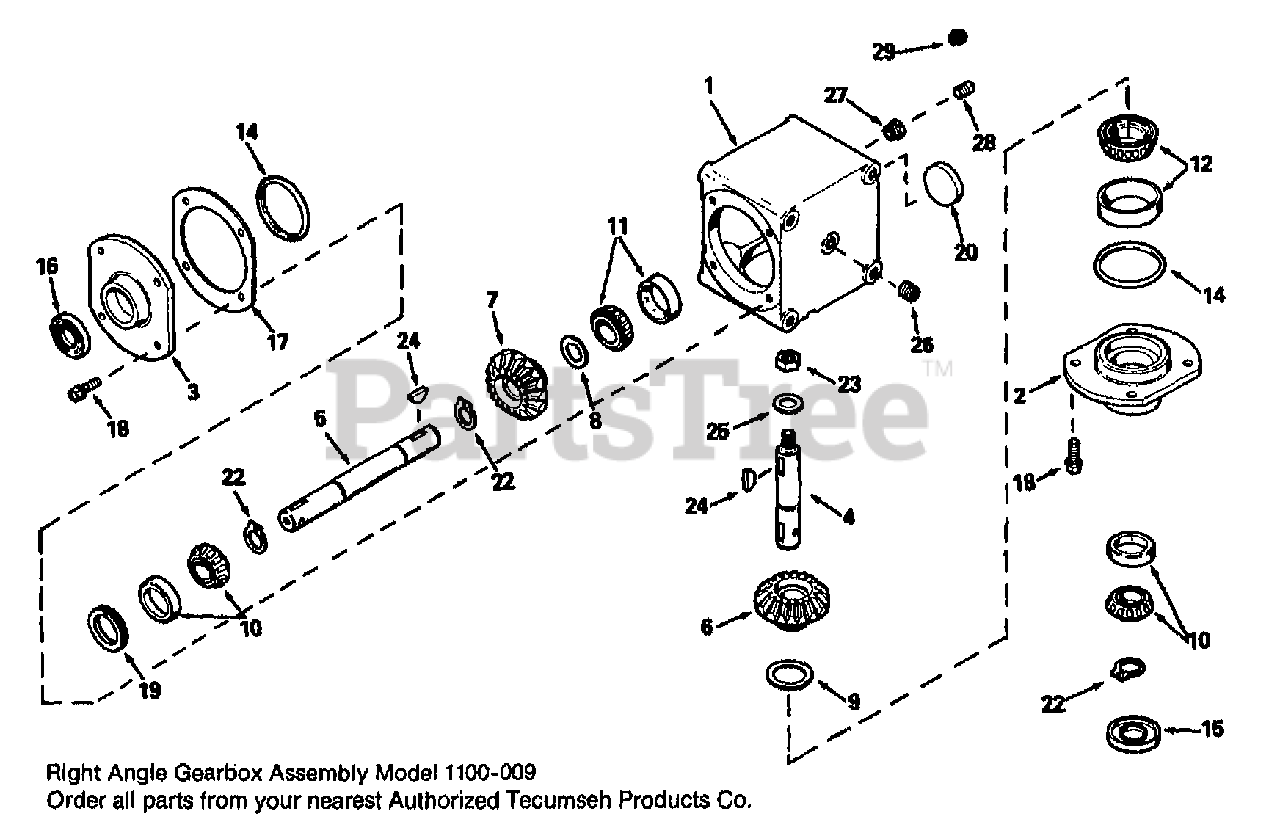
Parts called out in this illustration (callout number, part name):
4	OUTPUT SHAFT
5	INPUT SHAFT
6	BEVEL GEAR
7	BEVEL GEAR
8	SHIM STOCK
9	SHIM STOCK
10	BEARING & CUP
11	BEARING & CUP
12	BEARING & CUP
15	OIL SEAL
16	OIL SEAL
17	SHIM STOCK
19	LOAD RING
22	RET RING
24	WOODRUFF KEY
